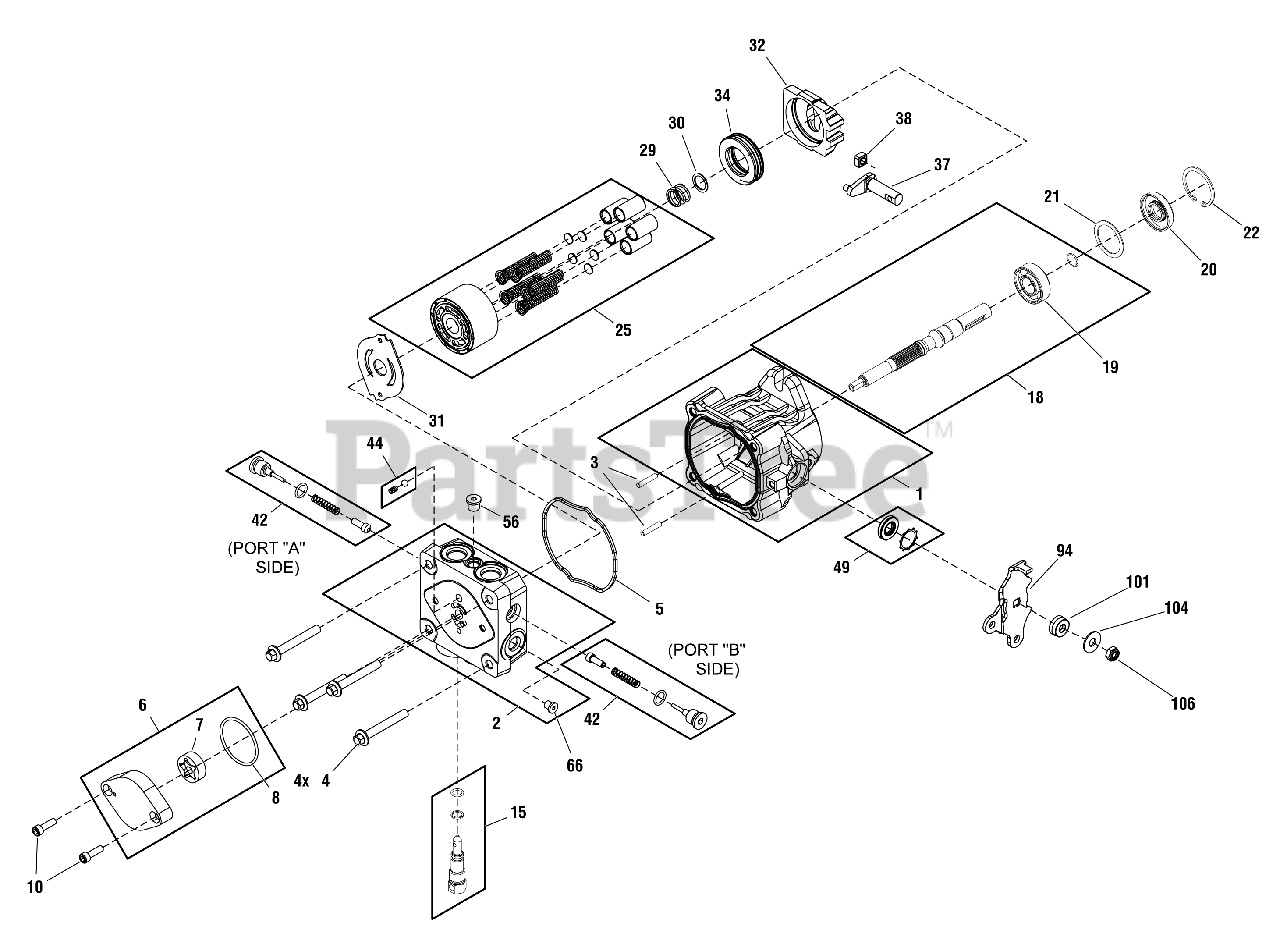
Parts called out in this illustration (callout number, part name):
1	Housing Kit
2	End Cap Kit (W/ Poppets, Standard Charge)
3	Straight Headless Pin
4	Hex Flange Bolt M8-1.25 X 60mm LG
5	Housing O-Ring
6	Charge Pump Kit (STD)
7	* STD Gerotor Assy (11 cu. In/rev D-Drive)
8	* O-Ring
10	Socket Head Screw M6 x 1.0-20mm Lg (STD Charge)
15	Bypass Valve Kit (Blank)
18	Pump Shaft Kit (Blind 15mm Keyway W/ Std Charge)
20	Lip Seal 17 x 40 x 7 PTC
22	Retaining Ring
25	Cylinder Block Kit
29	Block Spring
30	Block Thrust Washer
31	Valve Plate (Steel N-Tec:Black)
34	Ball Thrust Bearing
37	Trunnion Arm, Tapered Square
42	Check Valve Kit (0.031"Orifice)
44	Charge Relief Valve Kit (1/4" Plastic Ball & Spring)
49	Trunnion Seal / Retainer Kit
56	Straight Thread Plug
66	* 5/16" SAE Plug
94	* Arm,Control
101	* Spacer RTN
106	* Nut, Hex Lock 5/16-24 UNF
110	** Kit, RTN, STD
